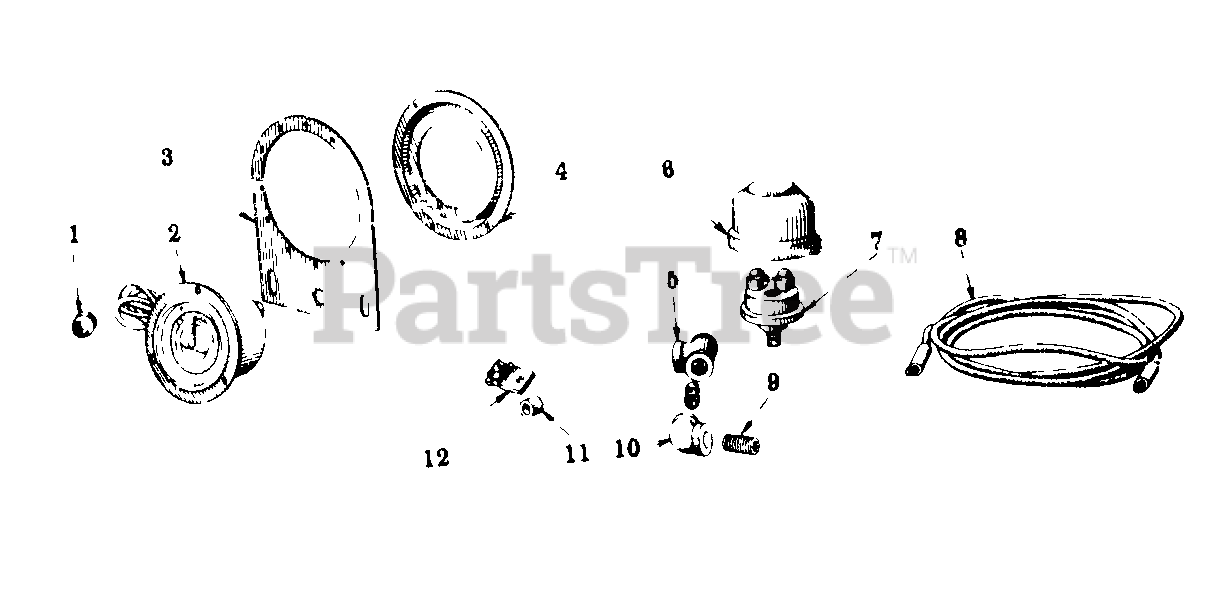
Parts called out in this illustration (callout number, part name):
1	GROMMET, RUBBER
2	METER ASSY, HOUR
3	BRACKET, HOUR METER MOUNTING
4	DAMPER, HOUR METER VIBRATION
5	TEE, 1/8 PIPE
6	SHIELD, PRESSURE SWITCH
7	SWITCH, HOUR METER PRESSURE
8	CABLE, PRESSURE SWITCH TO JUNCTION BLOCK
9	NIPPLE, 1/8 X 7/8 PIPE - LONG
10	ELBOW, 1/8 X 90 DEG STREET
11	SPACER, JUNCTION BLOCK
12	BLOCK, JUNCTION
